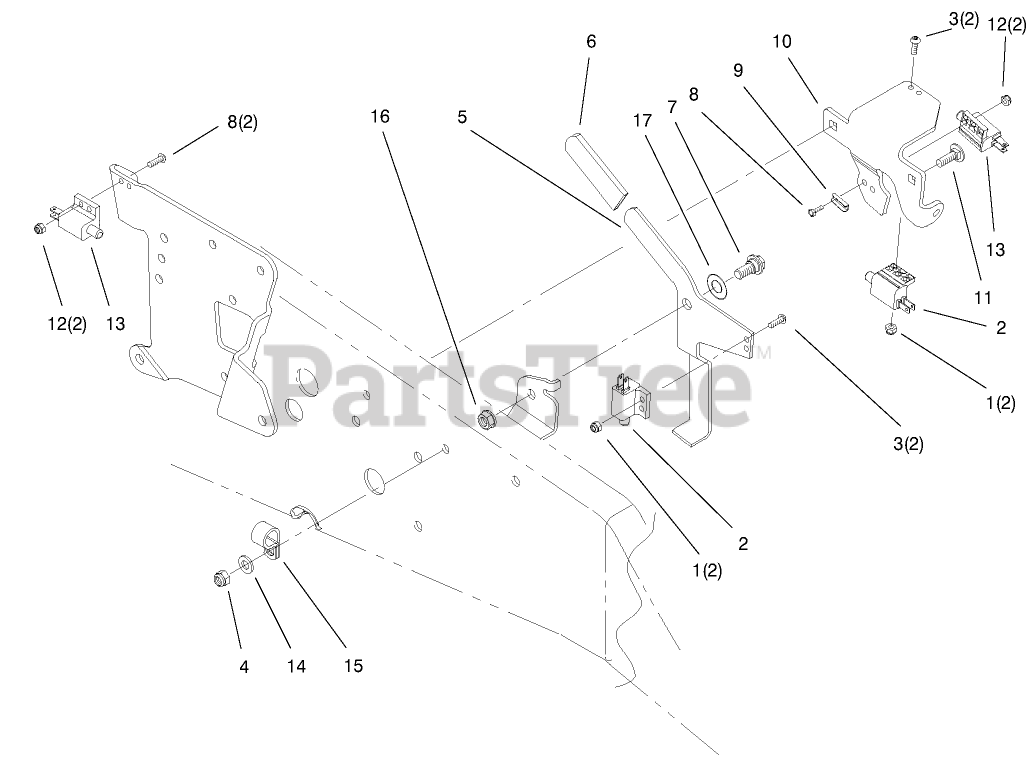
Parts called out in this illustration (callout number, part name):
1	NUT-LOCK, NI
3	SCREW-HSH
4	NUT-LOCK, NI
5	LATCH-BRAKE, PARKING
7	BOLT-SHOULDER
8	SCREW
9	RETAINER-SCREW
10	BRACKET-SWITCH
11	SCREW-CARR
12	NUT-LOCK
13	SWITCH-POLE, SINGLE
14	WASHER-PLAIN
15	CLAMP - R
16	NUT-HEX
17	WASHER
